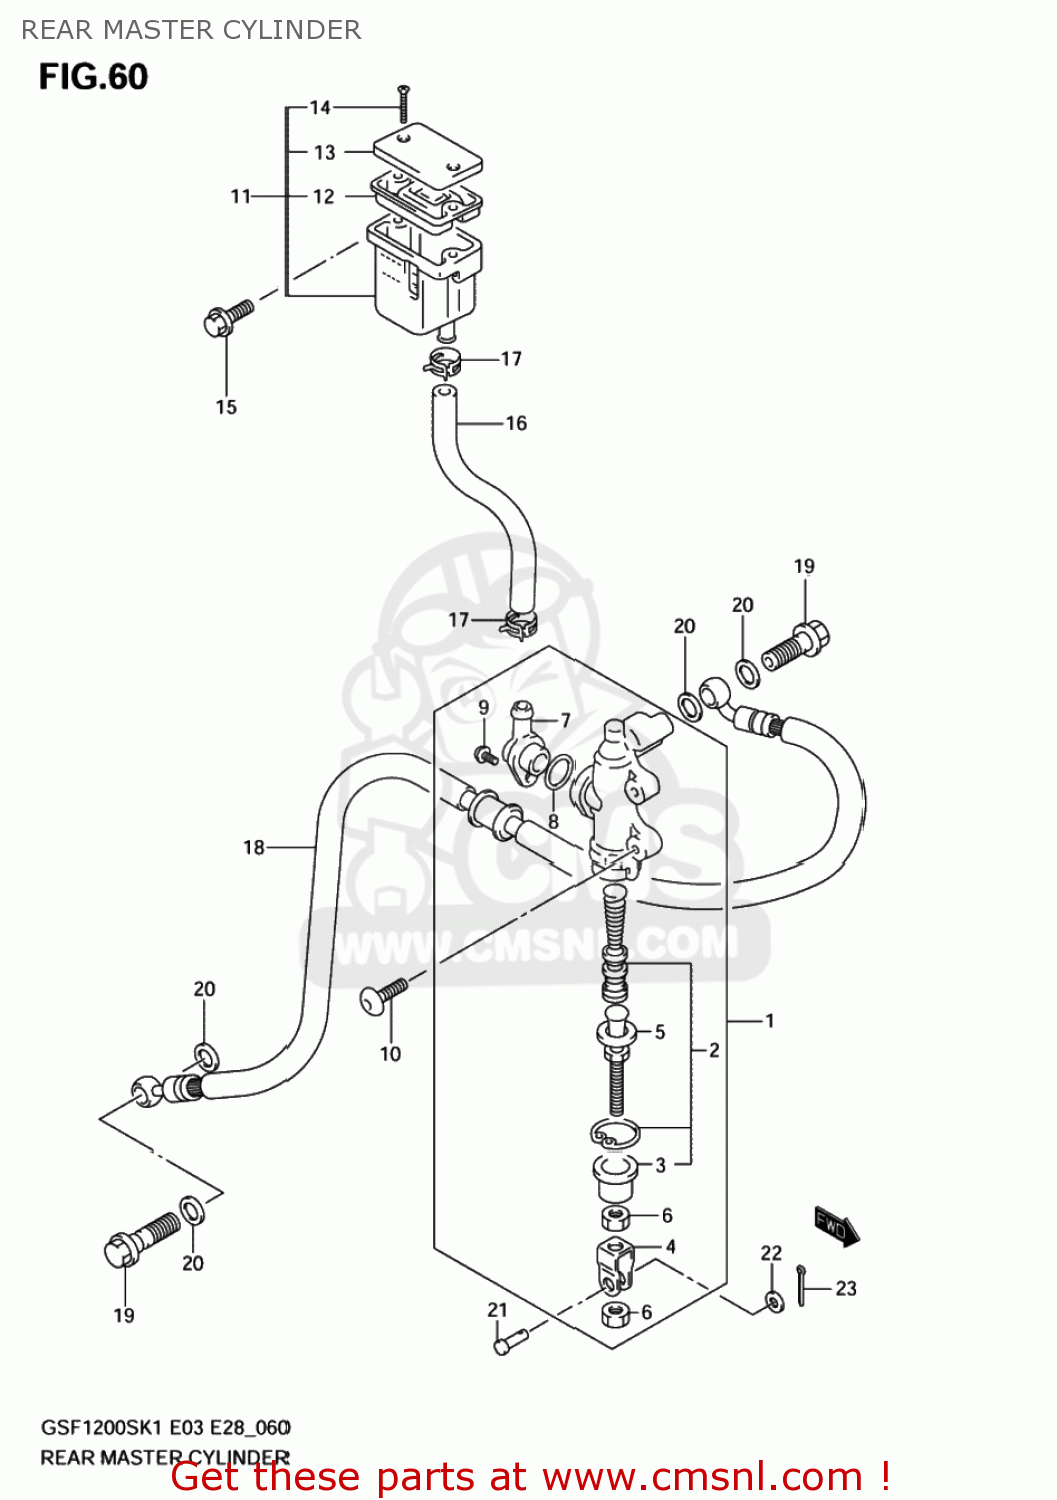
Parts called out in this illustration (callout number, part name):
1	CYLINDER ASSY,RR MASTER
2	PISTON/CUP SET
3	BOOT
4	YOKE
5	ROD,PUSH
6	NUT
7	CONNECTOR
8	O RING
9	SCREW
10	BOLT 8X20
11	TANK ASSY,RESERVOIR
12	DIAPHRAGM
13	CAP
14	SCREW
15	BOLT
16	HOSE,RR RESERVOIR TANK
17	CLIP
18	HOSE,REAR BRAKE
19	BOLT UNION
20	WASHER(10X15X1.5)
21	PIN
22	WASHER
23	PIN
